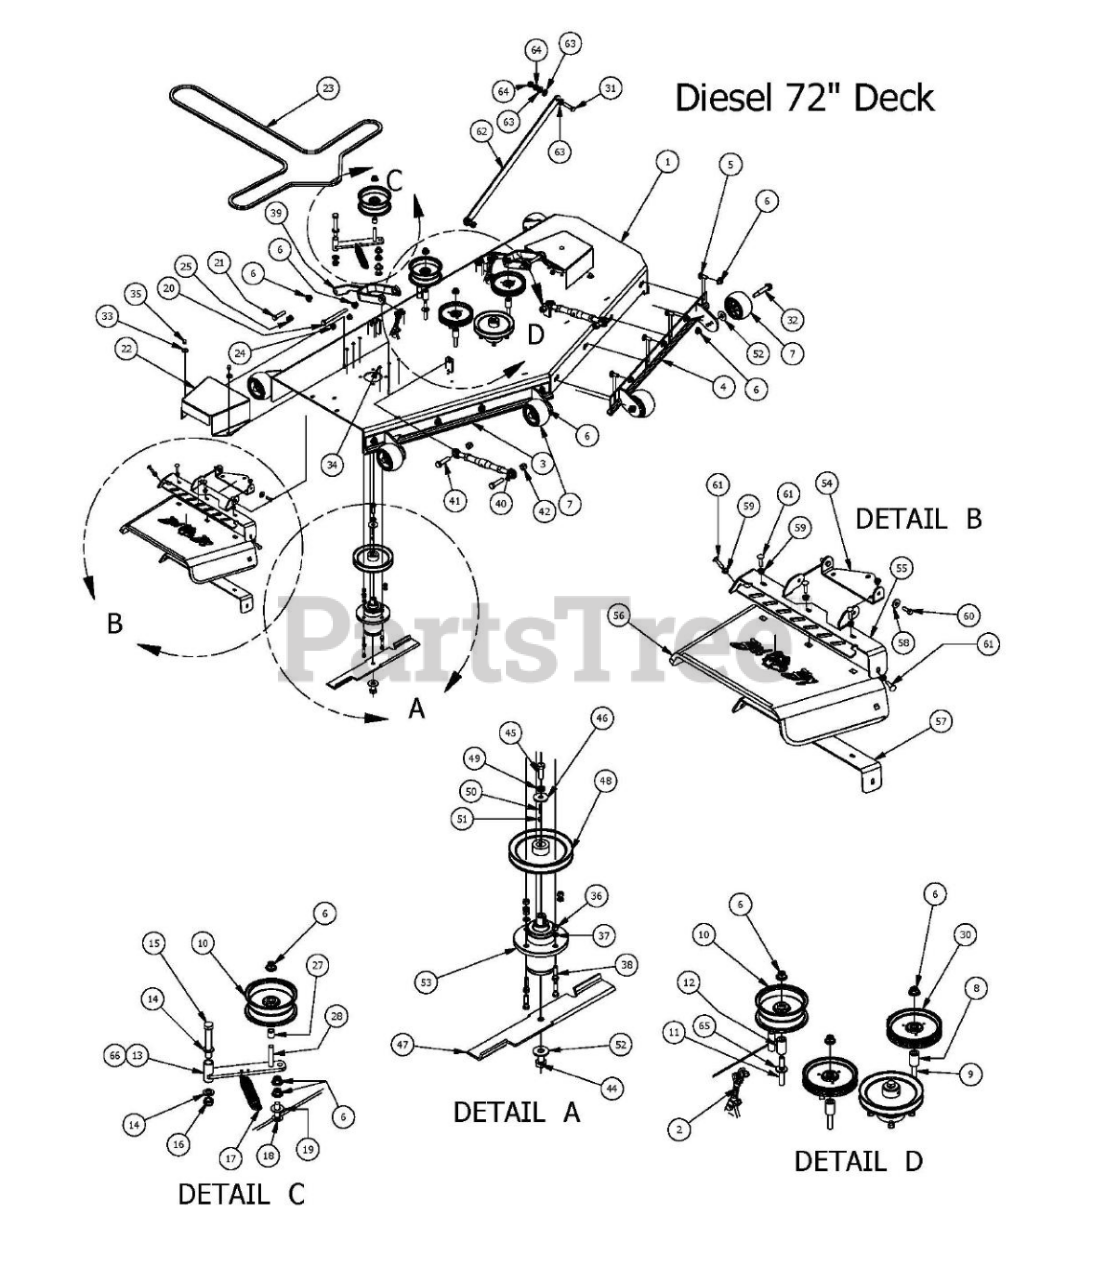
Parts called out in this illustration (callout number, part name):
1	72" (Deck Only)
2	5-Link Adjustable Deck Hange
3	72" Deck Adustable Front (Right)
4	72" Deck Adjustable Front (Left)
5	1/2" x 1 1/4 Carriage Bolt
6	1/2-13 Nylon Insert Flange Nut
7	Anti-Scalp Roller
8	Idler Pulley Standoff
9	1/2 x 3 1/2 Flange Bolt Grade 8
10	5 3/4" Deck Idler Pulley
11	1/2" x 4" Bolt (Grade 8)
12	1 3/4" Pulley Spacer
13	Deck Idler
14	.630 ID Plastic Washer
15	5/8" x 4" Hex Bolt
16	5/8-11 Nylon Insert Jam Half Nut
17	2015 Deck Idler Spring
18	1/2 x 2" Carriage Bolt
19	.517 Square Hole Round Washer
20	1/2" x 5 1/2" Bolt
21	1/2-13X 2-1/4 GR Hex Bolts
22	72 Spindle Cover
23	B252-50 Fits 2007 72" Diesel
24	Flange Bushing For Upper Deck Arm
25	Flange Bushing For Lower Deck Arm
26	Double Bearing For Spindle
27	Spacer 3/4 OD x 1/2 ID x 314 Length
28	1/2-13 x GR 5 Hex Bolt Zinc
29	Roller Support Tab Adjustable
30	5-3/4 Idler Pulley-Capitol Stampings
31	1/2-13x2 Grade 8 Hex Bolt
32	Deck Wheel Bolt
33	.360 ID Plastic Washer-Black
34	Black, Round Stick-On Rubber Bumpon
35	Acorn nut-pulley Cover
36	3/8" Hex Nut
37	3/8" Lock Washer
38	3/8" x 1 1/2" Hex Bolt
39	Deck Arm Assembly
40	Turnbuckle (Top Link)
41	5/8" x 2 1/2" Grade 5 Hex Bolt (Coarse)
42	5/8 Std NC Nylock Nut
43	Turnbuckle Bracket (deck)
44	5/8" x 1 1/2" Grade 8 Hex Bolt (Fine)
45	1/2"-20 x 1 1/2 - Grade 5 Fine Thread Bolt
46	1/2 Belleville Washer
47	72" High Lift Fusion Blade
48	7" Deck Pulley
49	1/2" Lock Washer
50	1/4" x 1" Key
51	5/16 Set Screw
52	Flat Washer
53	OUTLAW SPINDLE ASSEMBLY
54	Discharge Chute Hanger (deck mounted)
55	60" Discharge Chute Upper Hanger
56	Rubber Discharge Chute
57	60" Discharge Lower Bracket
58	.360 ID Plastic Washer
59	5/16-18 Nylon Flange Nut
60	5/16" x 1" Bolt
61	5/16" x 1 1/4" Carriage Bolt
62	Panhard Linkage Bar
63	.505 Nylon Spacer
64	1/2" Flange Nut
65	1/2" Washer (Grade 8)
66	Deck Idler Complete Assembly-Componets 6,10,13,27,28
